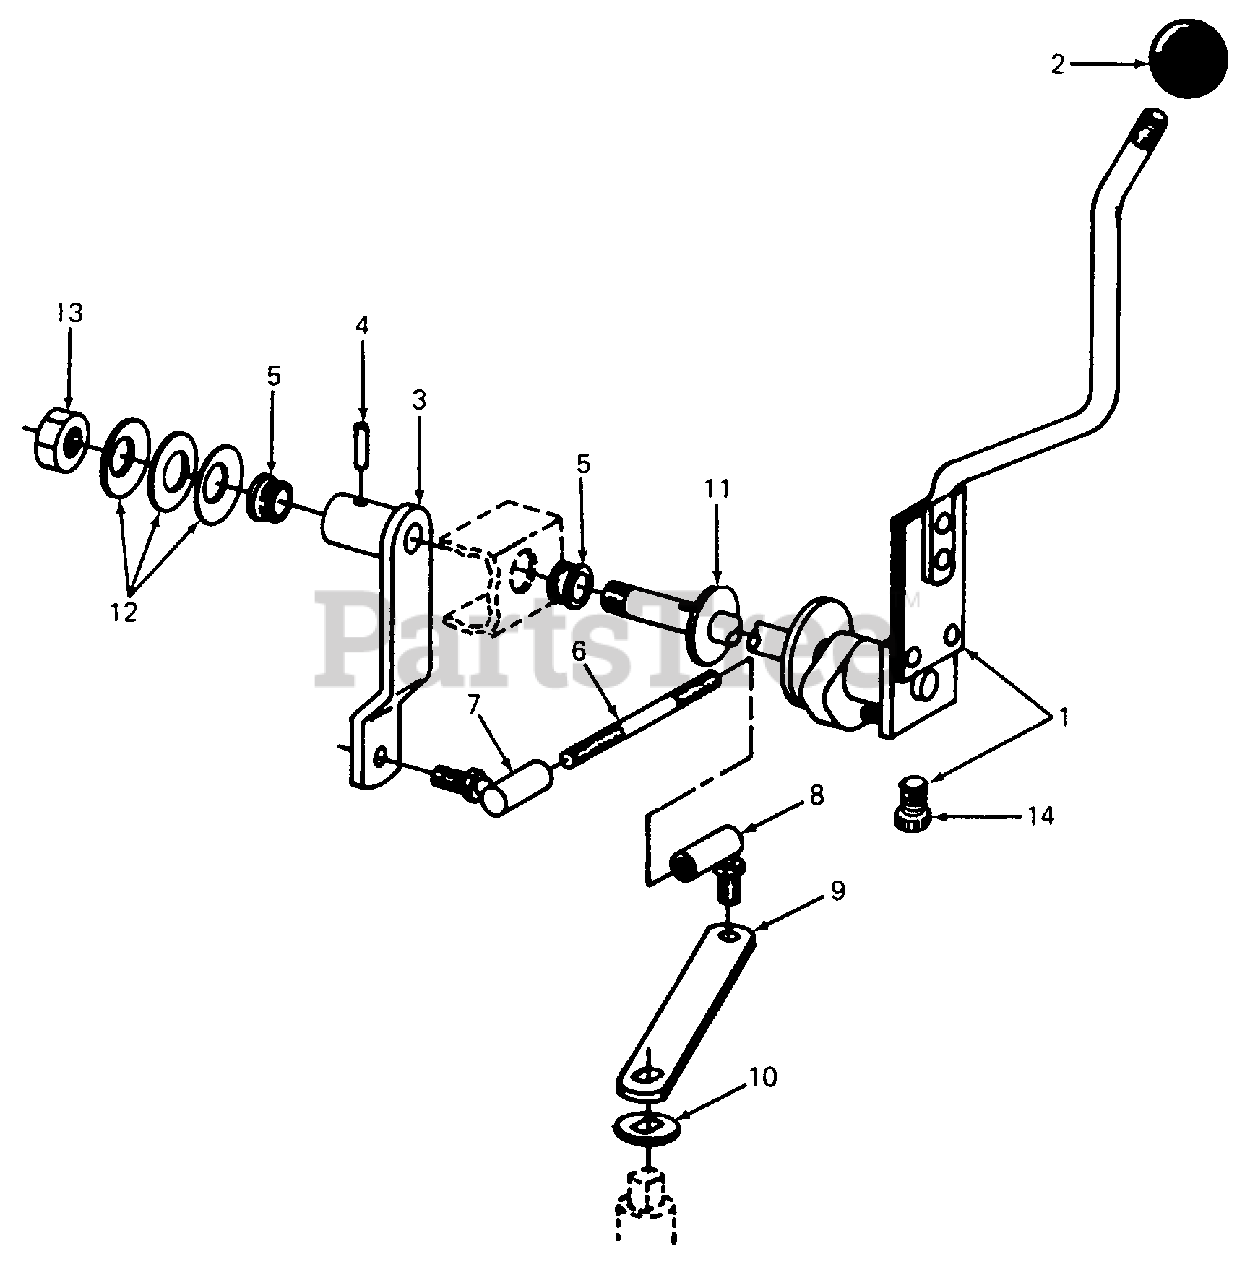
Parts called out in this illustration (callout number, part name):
1	Handle, Shifter Control
2	Knob, Shifter
3	Lever, Shifter
4	Pin, 3/16 X 1 Pln Slt-Spr
5	Bearing, Nyliner
6	Shaft, Shifter
7	Joint, 5/16 C-Z Type G Ball
8	Joint, 5/16 Pln Type G Ball (LH Thd)
9	Lever, Shifter
10	Washer, Shifter
11	Washer, Friction
12	Washer, .760 X 1.5 X .06 Belleville
13	Nut, 1/2 Cad P/T Lock GR 5
14	Screw, 1/4 X 1/2 Hex-Soc-Hd
